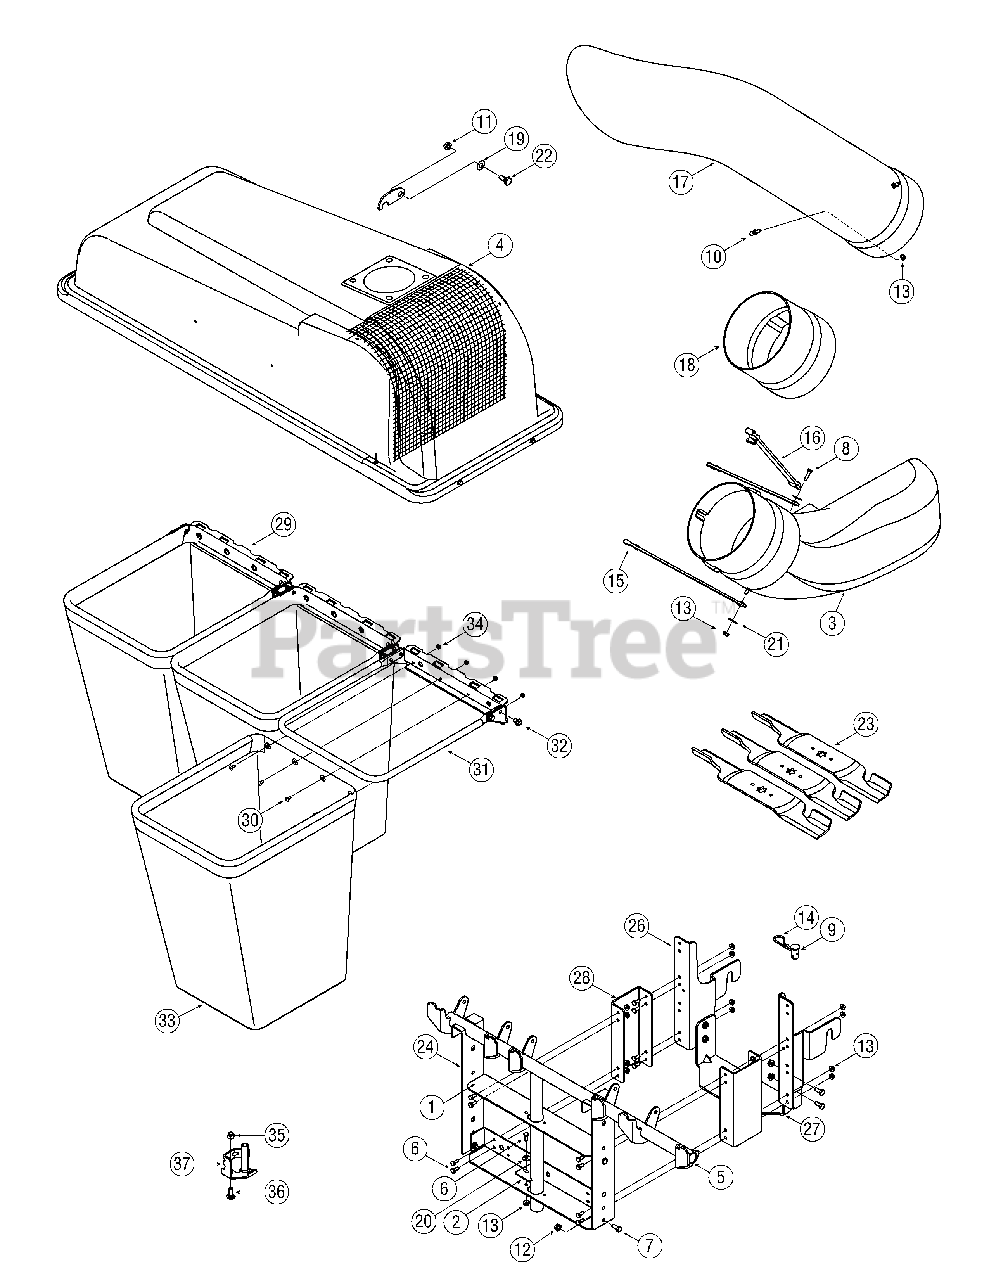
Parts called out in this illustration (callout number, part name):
3	Elbow Chute Assembly
4	Grass Catcher Cover Assembly
7	Hex Cap Screw, 5/16-18 x .75
8	Hex Cap Screw, 1/4-20 x 1.00
9	Clevis Pin
10	Grass Catcher Pin, 1/4-20
11	Hex Flange Lock Nut, 3/8-16
12	Hex Flange Lock Nut, 5/16-18
13	Hex Flange Lock Nut, 1/4-20
14	Internal Cotter Pin, .148 x 3
15	Chute Strap, 11.65
16	Retainer Strap Assembly
17	Chute Tube
18	Extension Tube
19	Belleville Washer
20	Bell Washer, .265 x .75 x .062
21	Flat Washer .265 x 1.0 x .030
22	Shoulder Screw, .50 x .27, 3/8-16
23	High Lift Blades 18.50"
23	High Lift Blades 18.50" (742-3044)
30	Screw, #10-24 x .5
33	Grassbag
34	Hex Sems Nut, #10-24
35	Hex Lock Nut, 3/8-16
36	Carriage Bolt, 3/8-16: 1.00
